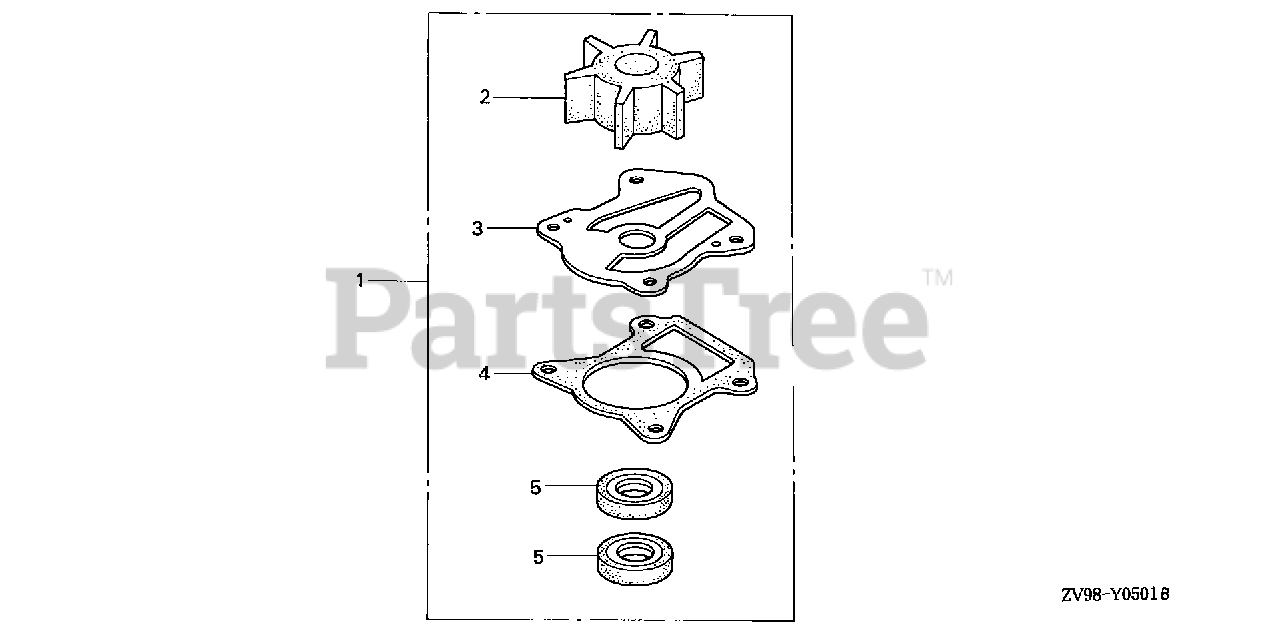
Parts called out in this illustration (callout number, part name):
1	IMPELLER KIT, WATER PUMP
2	IMPELLER, PUMP
3	GASKET B, IMPELLER
4	GASKET, WATER PUMP
5	SEAL, WATER (17X30X7)
